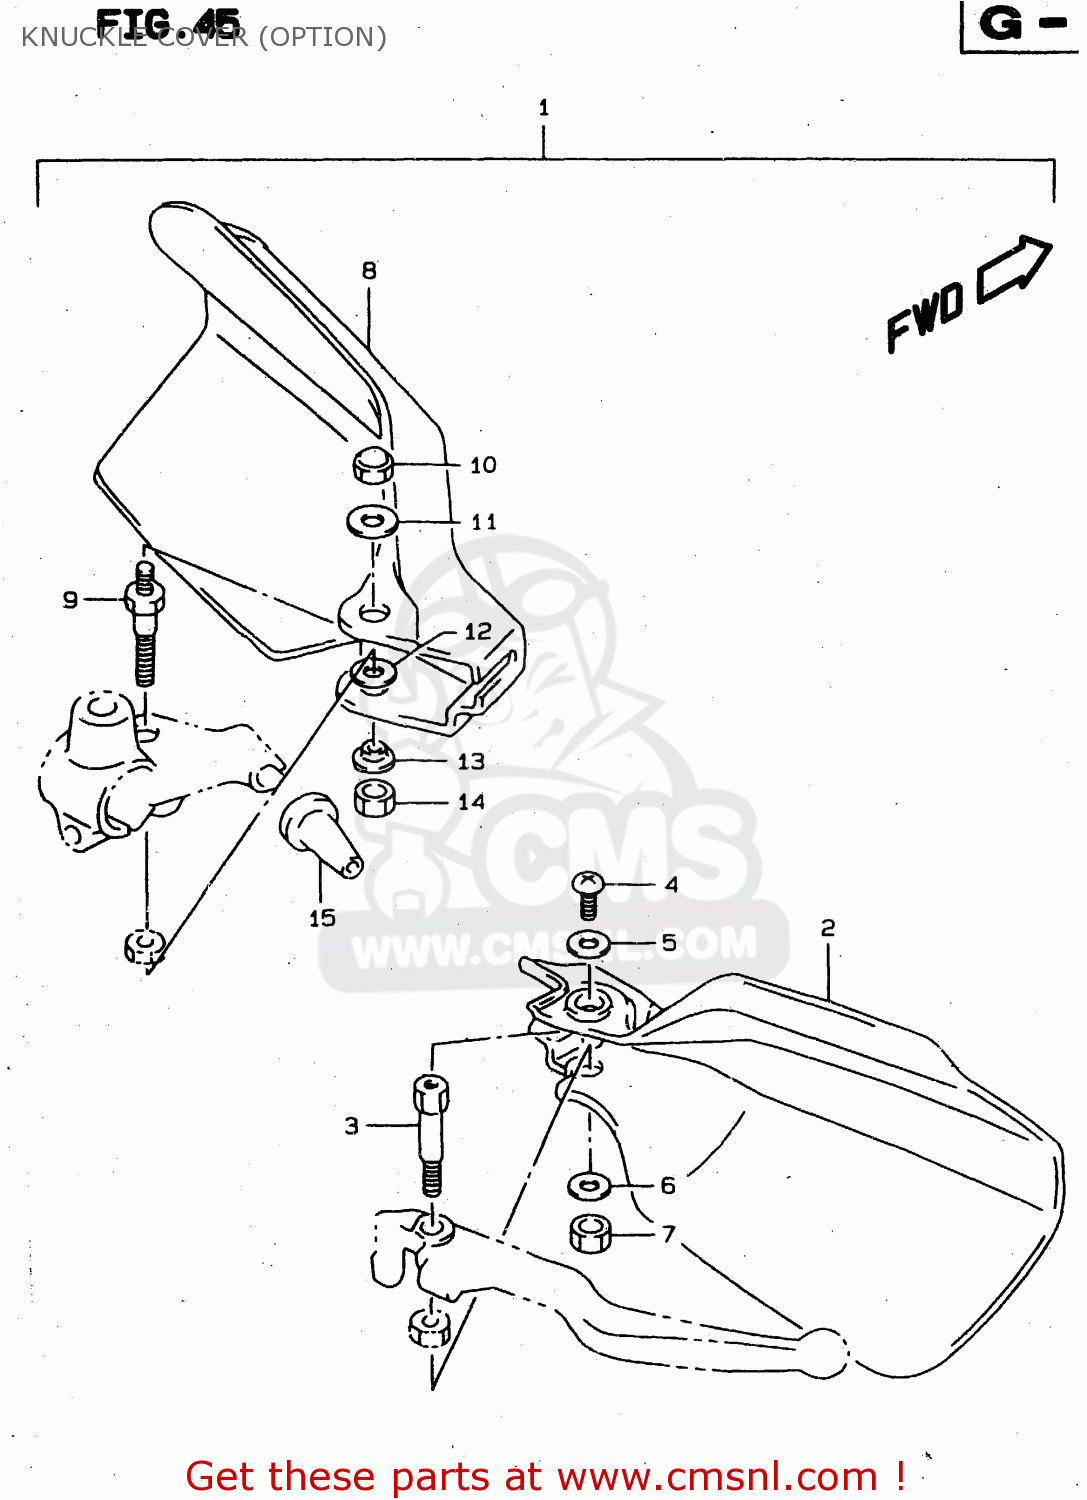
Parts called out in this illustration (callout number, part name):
1	COVER SET,KNUC
2	COVER,KNUCKLE,RIGHT
3	BOLT,BRAKE LEVER PIVOT
4	SCREW
5	WASHER(5.5X16X1.2)
6	WASHER(6.5X16X1.6)
7	NUT 6MM
8	COVER,KNUCKLE,LEFT
9	BOLT,CLUTCH LEVER PIVOT
10	NUT
11	WASHER(6.5X20X1.6)
12	WASHER(6.5X16X1.2)
13	WASHER
14	NUT 6MM
15	BOOT,CLUTCH CABLE
